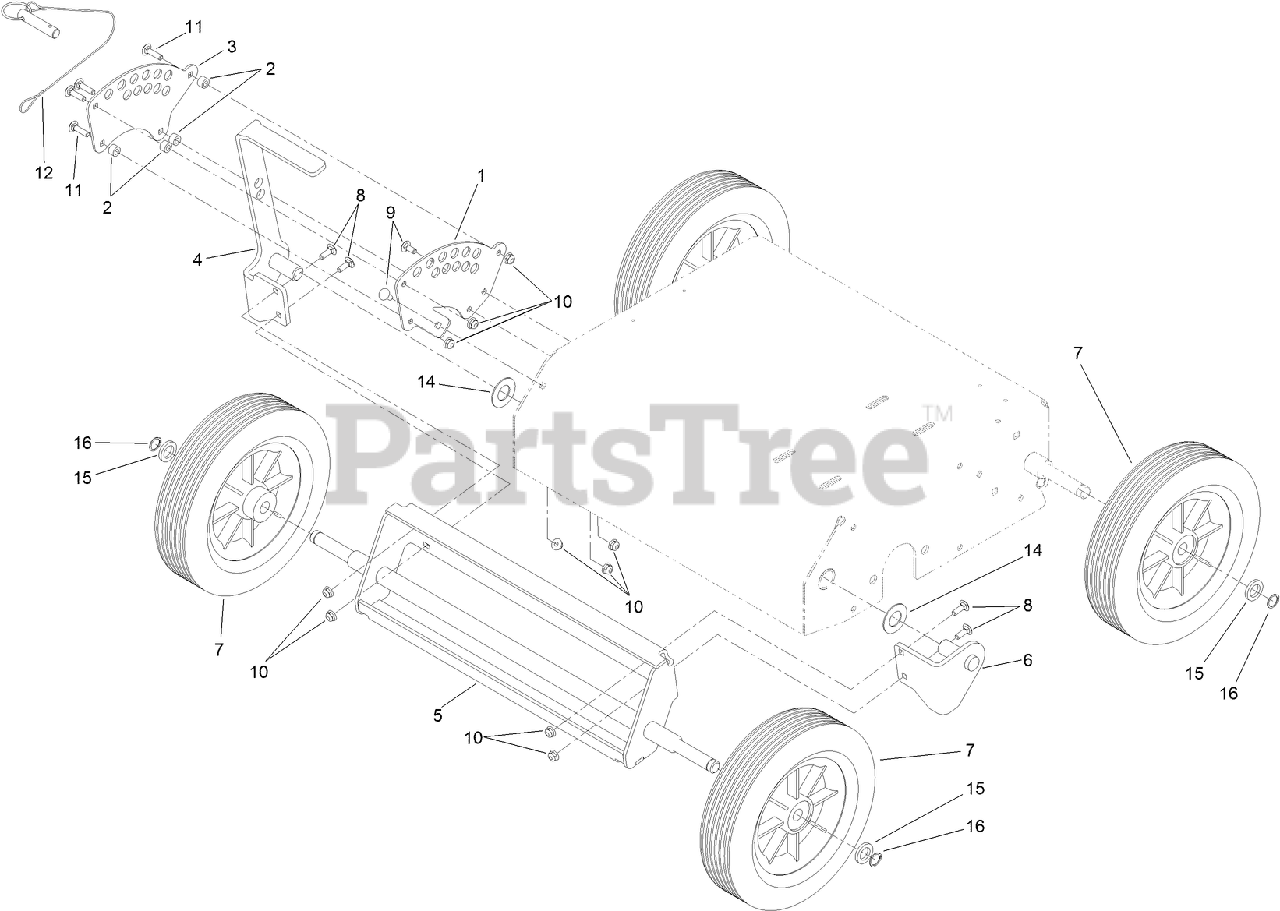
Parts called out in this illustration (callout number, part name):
1	BRACKET
2	SPACER
4	BRACKET-ADJUST, HEIGHT
5	BRACKET-WHEEL, HOC
6	BRACKET-WHEEL
7	WHEEL-TRANSPORT 10"
8	BOLT-CARR
9	SCREW-CARR
10	NUT-HF
11	SCREW-CARR
12	PIN-HITCH
14	WASHER-FLAT
15	SPACER-BEARING
16	RING-SNAP, EXTERNAL
